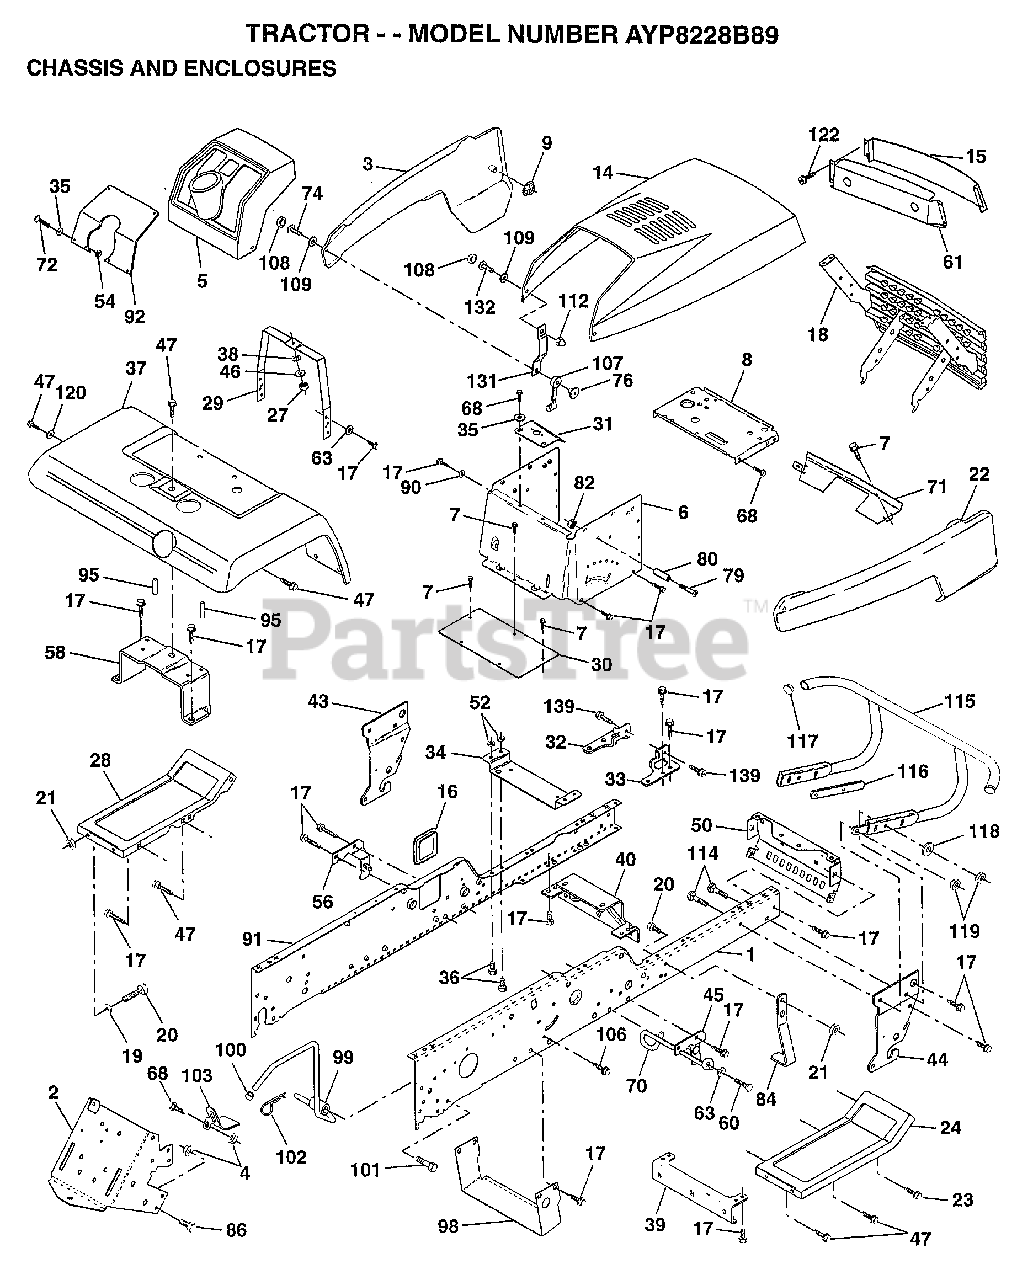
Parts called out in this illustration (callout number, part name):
1	"RAIL,FRAME RH"
2	DRAWBAR GT
3	"PANEL,ASM SIDE LH"
4	NUT.7/16
5	DASHBOARD BLACK
6	DASH LOWER
7	SCREW
8	SUPPORT.DASH.BTRY
9	PAL NUT LT
14	"HOOD ASM.,PNT"
15	LENS.BAR.CLEAR
16	COVER ACCESS
17	SCREW
19	WASHER
20	BOLT
22	PANEL ASM.SIDE RH
23	SCREW GTV
24	FOOTREST.RH.LT/GT
28	FOOTREST.LT.LT/GT
29	DASH.SUPT.YP/HUSQ
30	SADDLE.HYDRO.95
31	BRKT SUPT 1-PC VG
32	BKRT.PIVOT.CHASSIS.LH
33	BKRT.PIVOT.CHASSIS.RH
34	BRACKET.ENG.SUPT.
35	WASHER
36	BOLT
38	LOCKWASHER
39	BRACKET.AXLE.FRT.
40	"BRKT SUPPORT,AXLE"
43	BRACKET.SUS.FT.LH
44	BRACKET.SUS.FT.RH
45	BRACKET ASM., SUSP CHASSIS RH
46	WASHER PM
47	SCREW LT
50	"BRKT CHASSIS,FRNT"
56	BRACKET ASM., SUSP CHASSIS LH
58	BRKT.ASM.FENDER
60	SCREW
61	BEZEL.ASM.
63	WASHER
70	GUIDE.BELT.MID.SP
72	SCREW
74	SCREW
76	WELDNUT
79	SCREW
80	SPACER LT
84	STOP.OVER.CENTER
86	BOLT
90	LOCKWASHER
91	"RAIL FRAME,LH"
92	"PLATE DASH,SLKSCR"
95	NUT-PUSH YT
98	BRACKET SKID CHAS
99	ROD BYPASS
101	SCREW LT
103	LOCK BYPASS BRKT
107	HOOD LATCH T
108	SNAP CAP LT
109	WASHER LT
112	ACORN NUT RB
114	BOLT.3/8-14X1.25
115	BUMPER.ASM
116	BRACKET.EXT.BUMP.
117	PLUG.PLASTIC
118	WASHER
120	WASHER HYT
122	SCREW.HEX.WS.HD
131	BKT.SPT.HOOD/PANL
132	SCREW.10-24X3/8.
139	BOLT.SHOULDER.5/16-18
